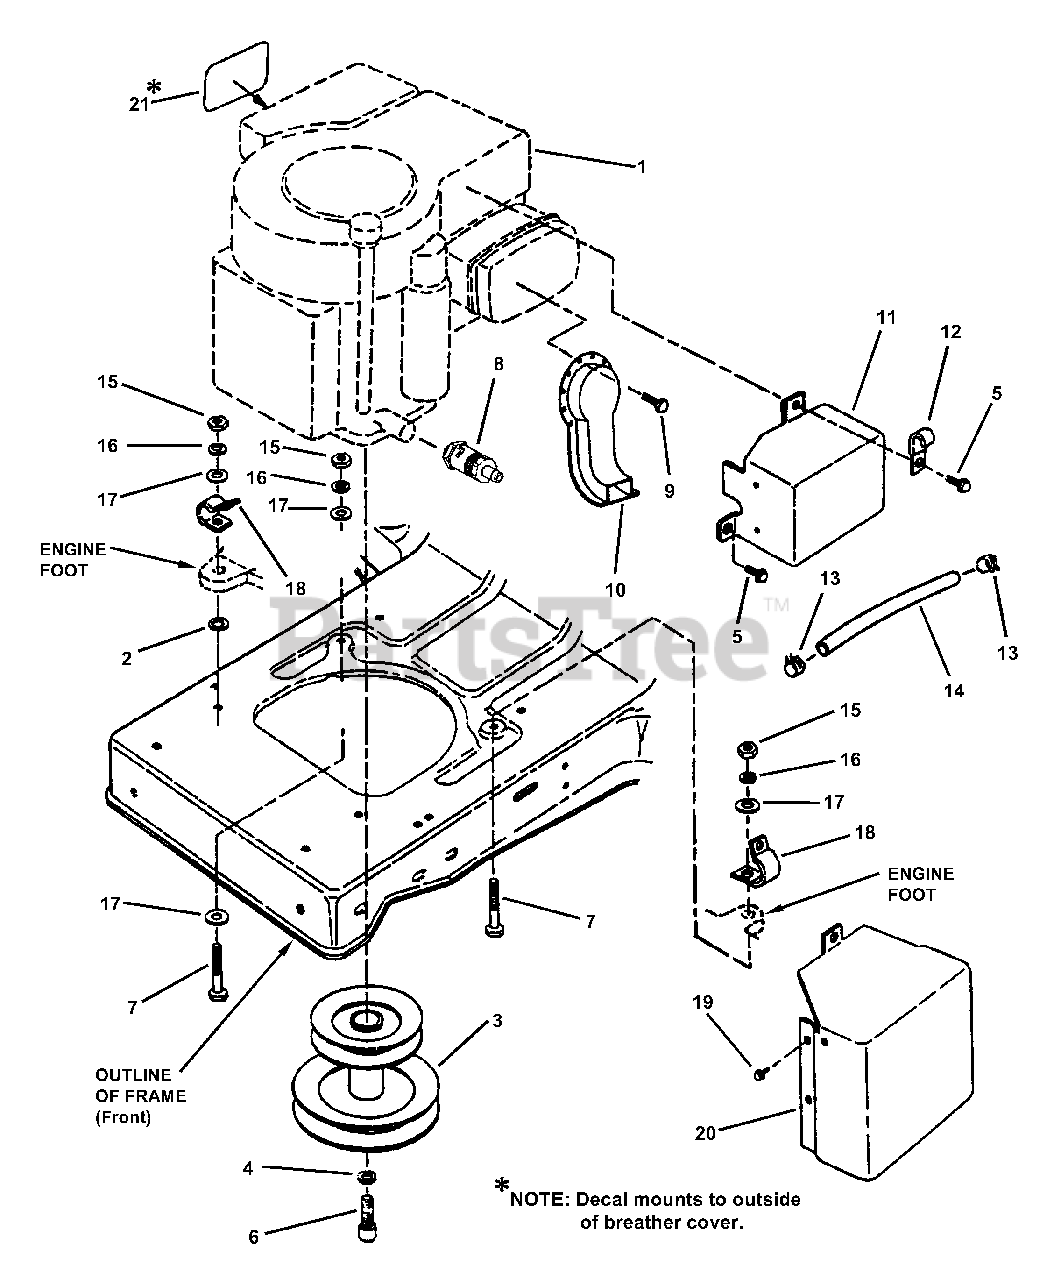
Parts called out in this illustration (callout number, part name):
2	WASHER, 5/16 Internal Tooth Lock
3	ASSEMBLY, Engine Pulley (LT145H33GBV & ELT145H33GBV)
3	ASSEMBLY, Engine Pulley (LT145H38GBV & LT150H38GBV)
4	WASHER, 7/16 Split Lock
5	BOLT, 1/4-20 x 1/2" Hex Flange Lock, Grade 5
6	SCREW, 7/16-20 x 1" Socket Head Cap
7	SCREW, 5/16-18 x 1-3/4" Hex Head Cap, Grade 5
8	ASSEMBLY, Oil Valve
9	SCREW, #8-18 x 1/2" Hex Head, Self-Tapping
10	EXTENSION, Muffler
11	HEAT SHIELD, Muffler
12	CLIP, "J" Type
13	CLAMP, Fuel Line
14	LINE, Fuel, 14" Long
15	NUT, 5/16-18 Hex, Grade 5
16	WASHER, 5/16 Split Lock
17	WASHER, 5/16 Flat
18	CLIP, Wiring Harness
19	SCREW, #10-24 x 5/8" Self-Tapping
20	HEAT SHIELD, Muffler (European Models)
21	DECAL, Warning Speed Setting
